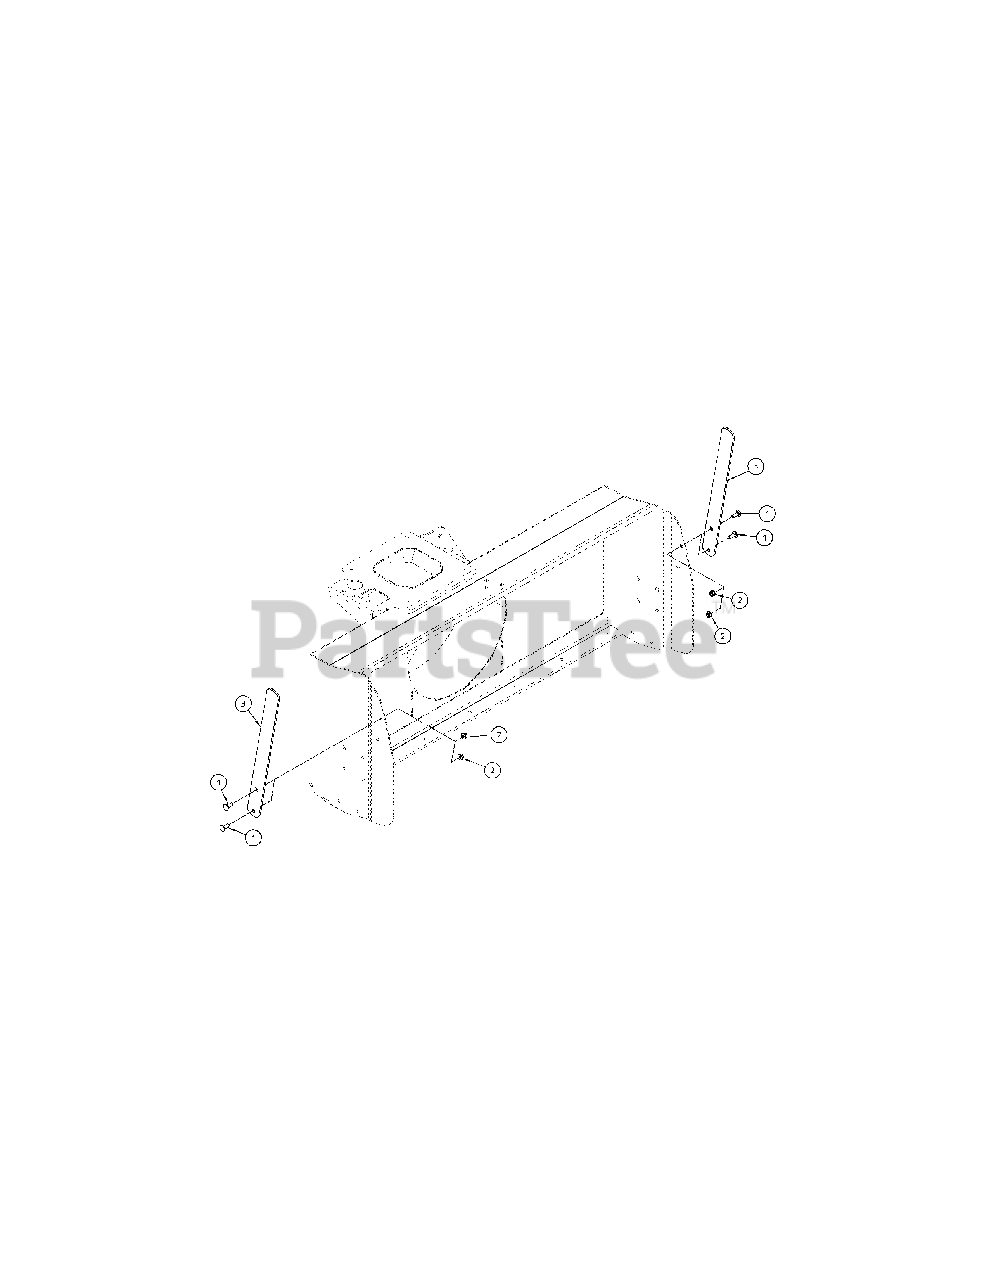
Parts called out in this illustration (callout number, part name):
1	Carriage Bolt, 3/8-16 x 1.0
2	Lock Nut, Flange 3/8-16
3	Plate, Drift Knife
